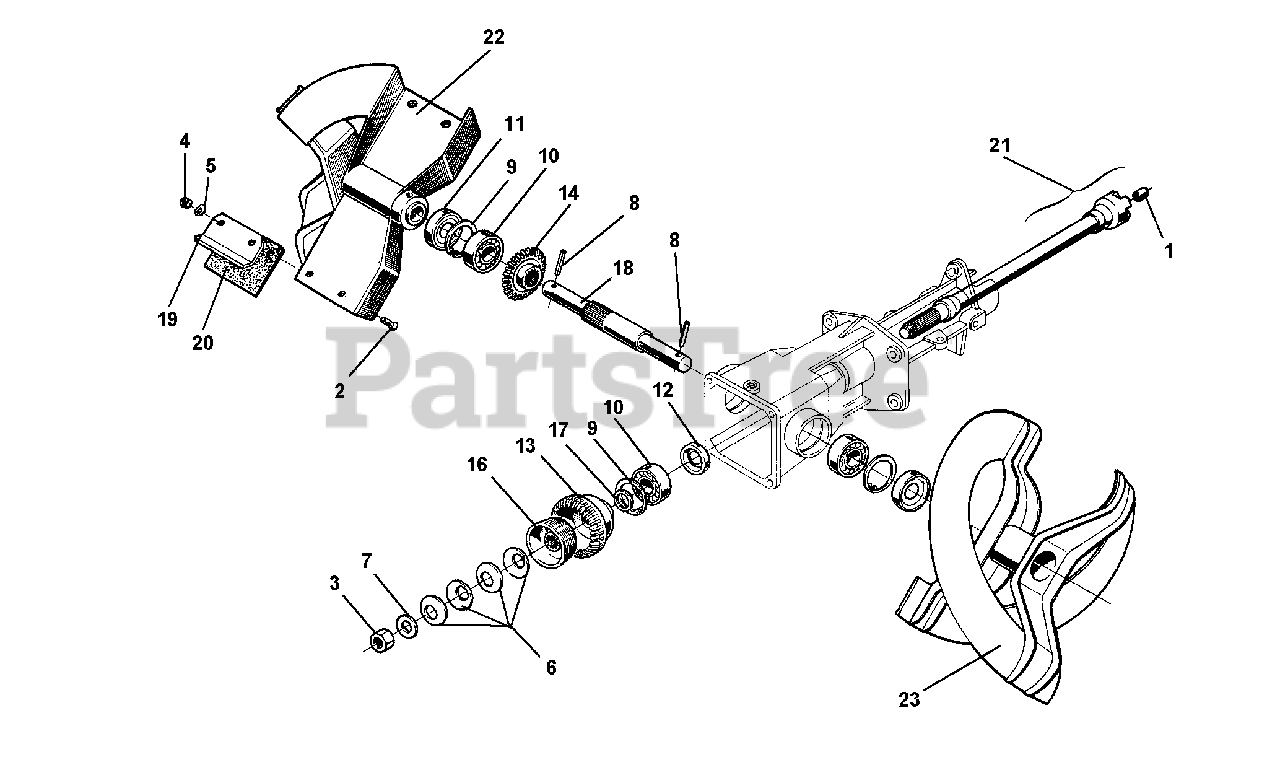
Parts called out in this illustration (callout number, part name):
2	SCREW TSVEI M6 X 20
3	NUT M14 X 1.5
4	SELF LOCKING NUT M6
5	WASHER, FLAT 6.4
6	SPRING 40 X 20.4 X 1.5
7	WASHER, LOCK 15
8	SPRING PIN 6 X 50
9	CIRCLIP, INTERN. D 47
10	BEARING 20 X 47 X 14 6204
11	OIL SEAL 20 X 47 X 7
12	OIL SEAL 25 X 40 X 7
13	CONICAL WHEEL
14	CONICAL WHEEL
15	SNOW THROWER SUPPORT
16	CONE CLUTCH
18	TURBINE SHAFT
20	RUBBER FLAP
22	R.H. TURBINE
23	L.H. TURBINE
